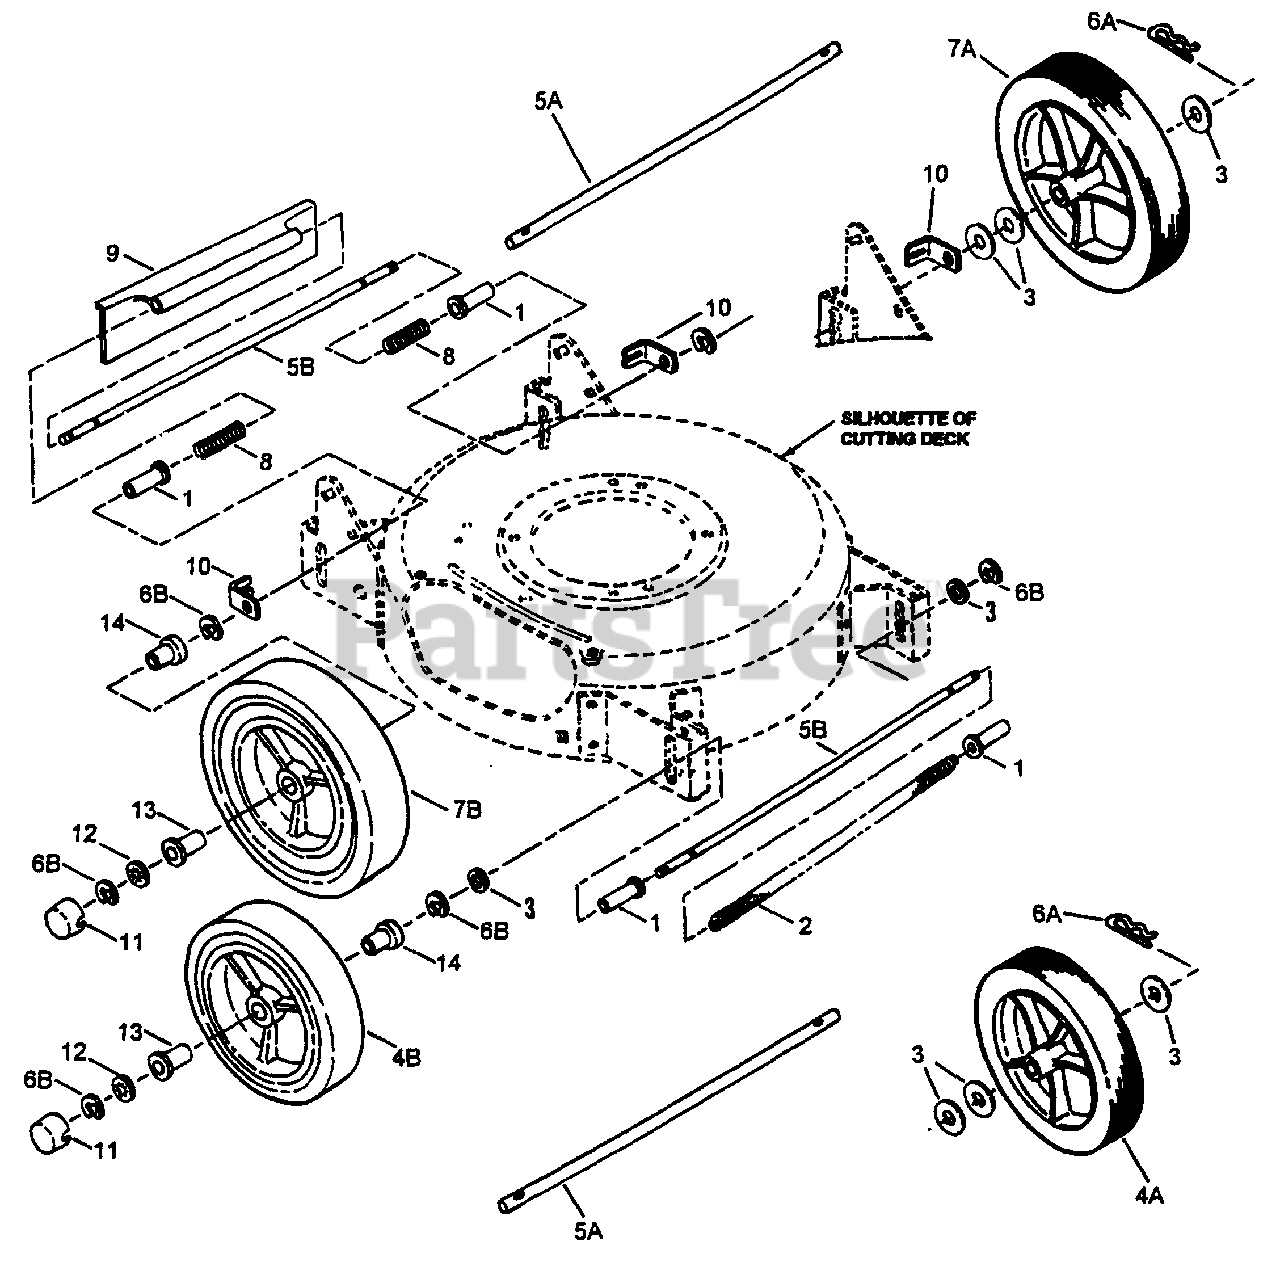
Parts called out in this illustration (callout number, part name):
1	BUSHING, Height Adj.
2	SPRING, Front Axle
3	WASHER, 3/8" Flat
4A	WHEEL, Front, 7 x 1.50"
4B	WHEEL, Fr., 7 x 1.75" Ball Brg.
5A	AXLE, 3/8 x 19-5/8
5B	AXLE, 3/8" x 19-3/8"
6A	PIN, 1/16" x 15/16 Hair
6B	RING, 3/8 Retaining
7A	WHEEL, Rear 8 x 1.75"
7B	WHEEL, Rear 8 x 2.00 Ball Brg.
8	SPRING, Rear Guard
9	GUARD, Rear Foot
10	CLIP, Rear Guard
11	HUB-CAP
12	RETAINER, Push-On
13	BUSHING, Wheel
14	BUSHING, Wheel
